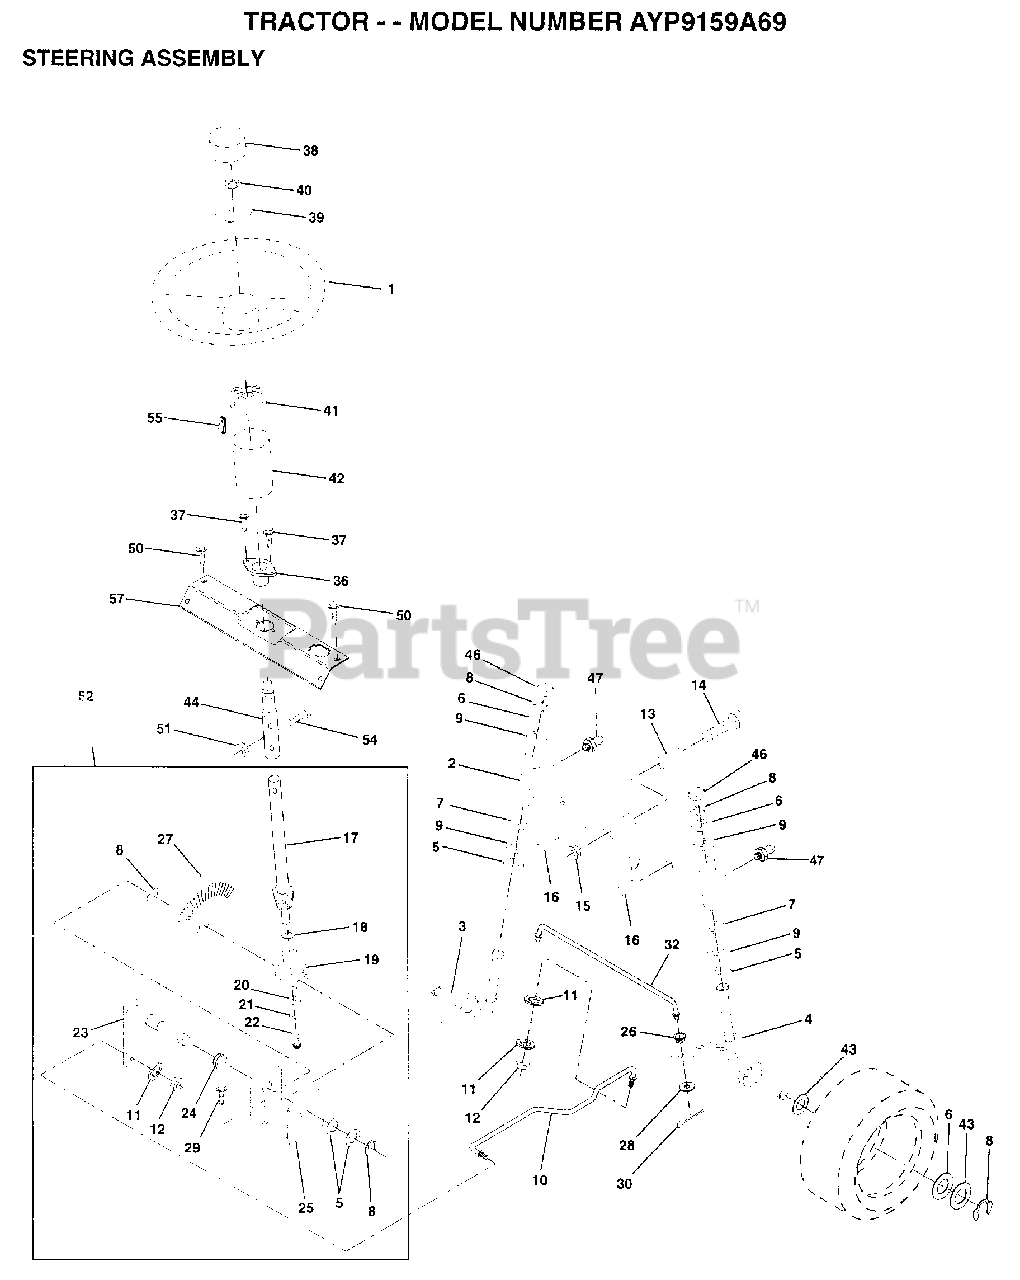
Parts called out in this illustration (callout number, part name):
1	WHEEL STR AYP BLK
2	AXLE ASM FRONT
3	SPINDLE LH
4	SPINDLE RH
5	WASHER .T
6	WASHER
7	WASHER
8	RING
9	COL. SRTG. BEAR.
11	LOCKWASHER
13	BEARING
14	BOLT HEX 5/8-11
15	"NUT-LOC,FLANGE LT"
16	AXLE PIN
17	SHAFT ASM STEERIN
18	THRUST WASHER
19	SUPPORT.SHAFT
21	LOCKWASHER
22	SCREW.SCKTHD.CAP
24	NYLINER T
25	"BRKT,STEERING"
26	BUSHING.DRAGLINK
27	GEAR SECTOR
28	WASHER
29	SCREW
30	COTTER PIN
32	TIE ROD
38	CAP STEER AYP
39	WASHER T
40	GRIPCO NUT
41	ADAPTER-WHEEL LT
42	BOOT SHAFT STEER
43	WASHER
46	CAP
47	ZERK M
50	SCREW HEX CRT
51	NUT
54	BOLT
55	CLIP TINNERMAN
57	SUPPORT SHAFT STR
